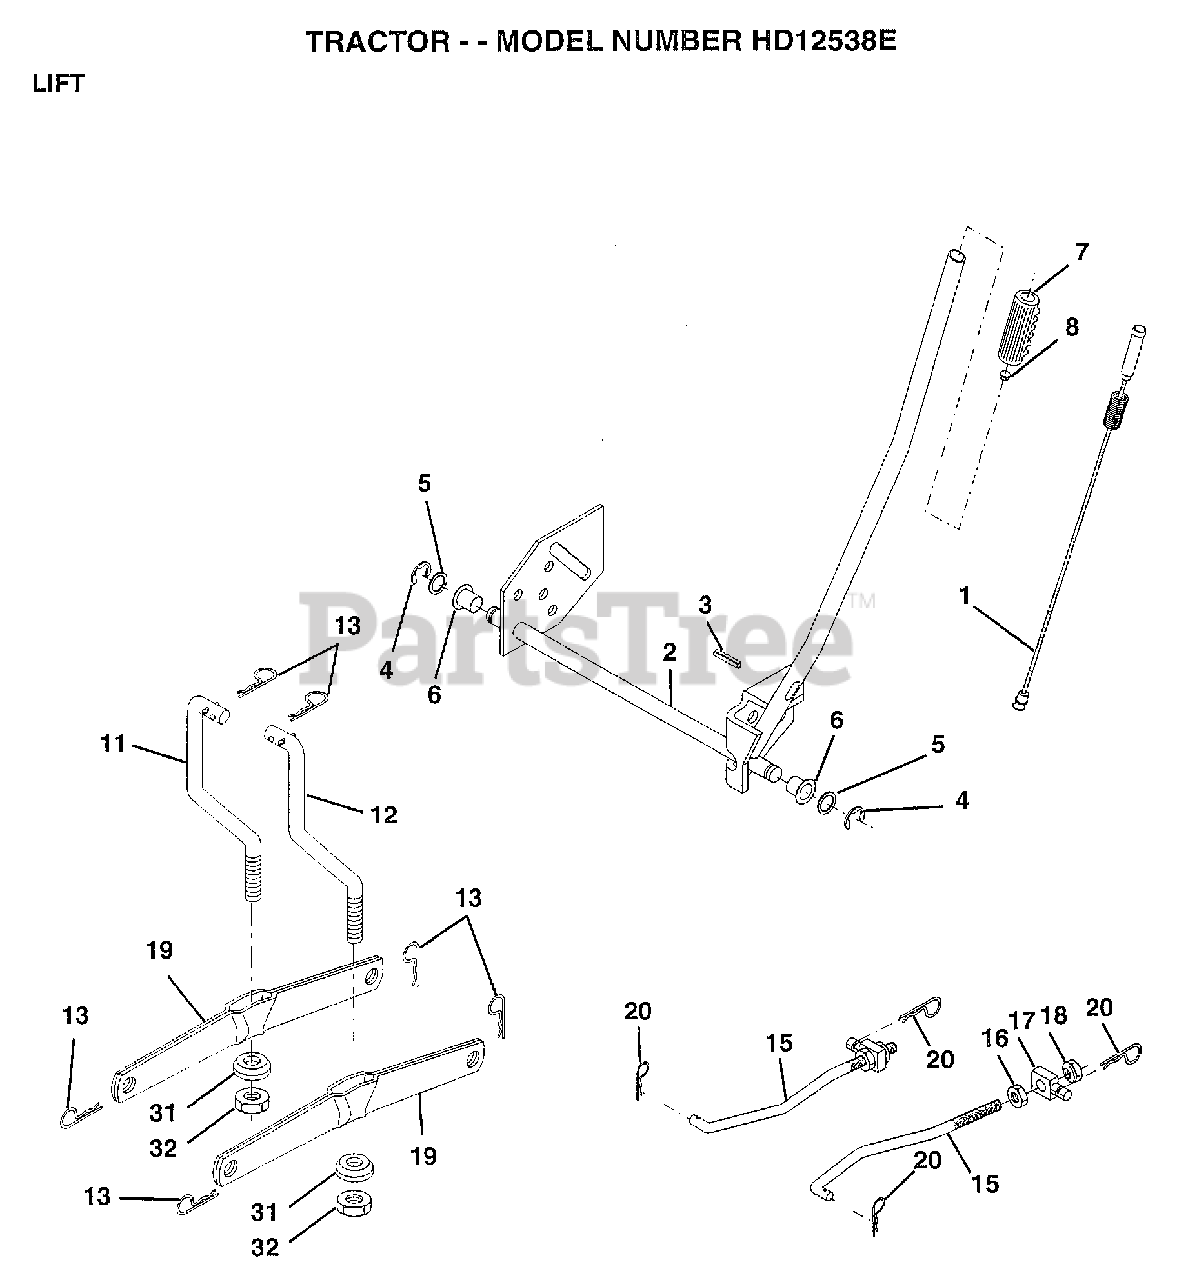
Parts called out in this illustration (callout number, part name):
1	WIRE ASM W.SPRING
2	"SHAFT ASM LIFT,RH"
3	PIN-GROOVE LT
5	WASHER
6	NYLON BEARING
7	GRIP
15	LINK.FRONT
16	NUT
17	TRUNION
18	NUT.LK.W/WSH.1/2.
19	ARM SUSP REAR
20	RETAINER.SPRING
31	BEARING PVT LH
32	NUT.CROWNLOCK.3/8
